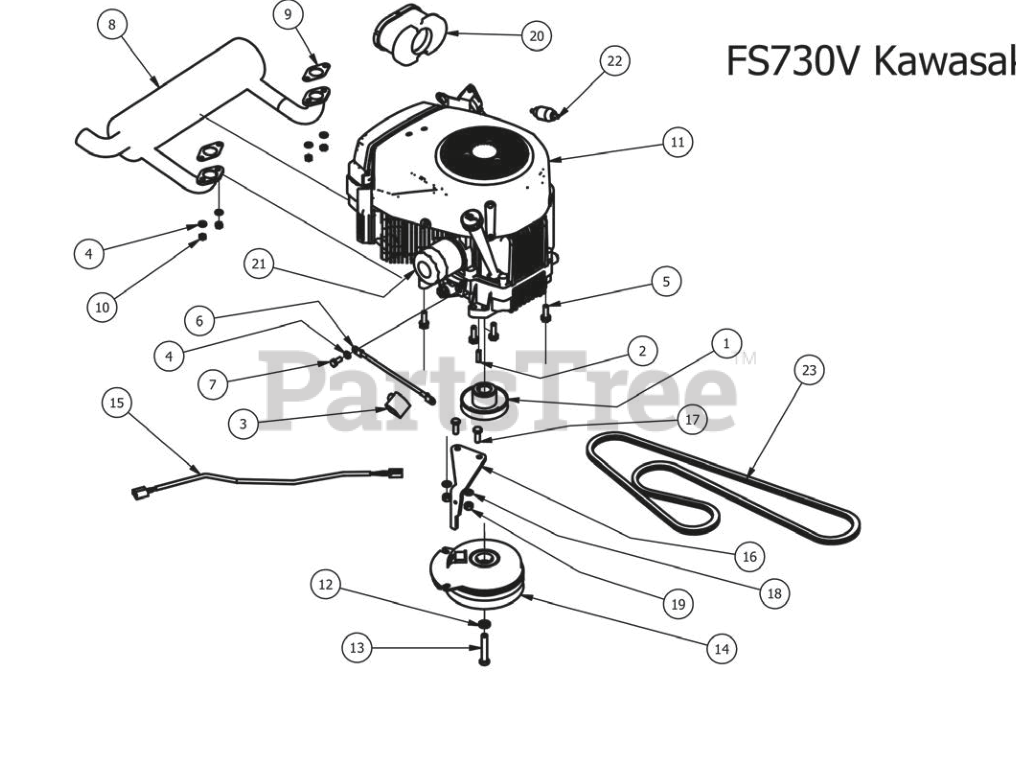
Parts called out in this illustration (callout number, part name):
1	3-3/4" Motor Pulley
2	1/4" x 1" Key
3	Black Boot For ground cable
4	5/16" Lock Washer
5	3/8 x 1 1/8 bolt
6	Starter to chassis cable
7	M8x1.20x20MM Hex head bolt
8	FS730V Kawasaki Exhaust-726cc
9	Exhaust gasket
10	M8-1.25 Zinc Nut
11	FS730V Engine
12	7/16" Lock Washer
13	7/16" x 2 1/2" Hex Bolt
14	Clutch Assembly
15	Clutch Pigtail
16	PTO Engager Holder
17	3/8" x 1" Hex Bolt
18	3/8" Lock Washer
19	3/8" Hex Nut
20	Kaw air Filter For Engine
21	Oil Filter
22	Universal inline Fuel Filter
